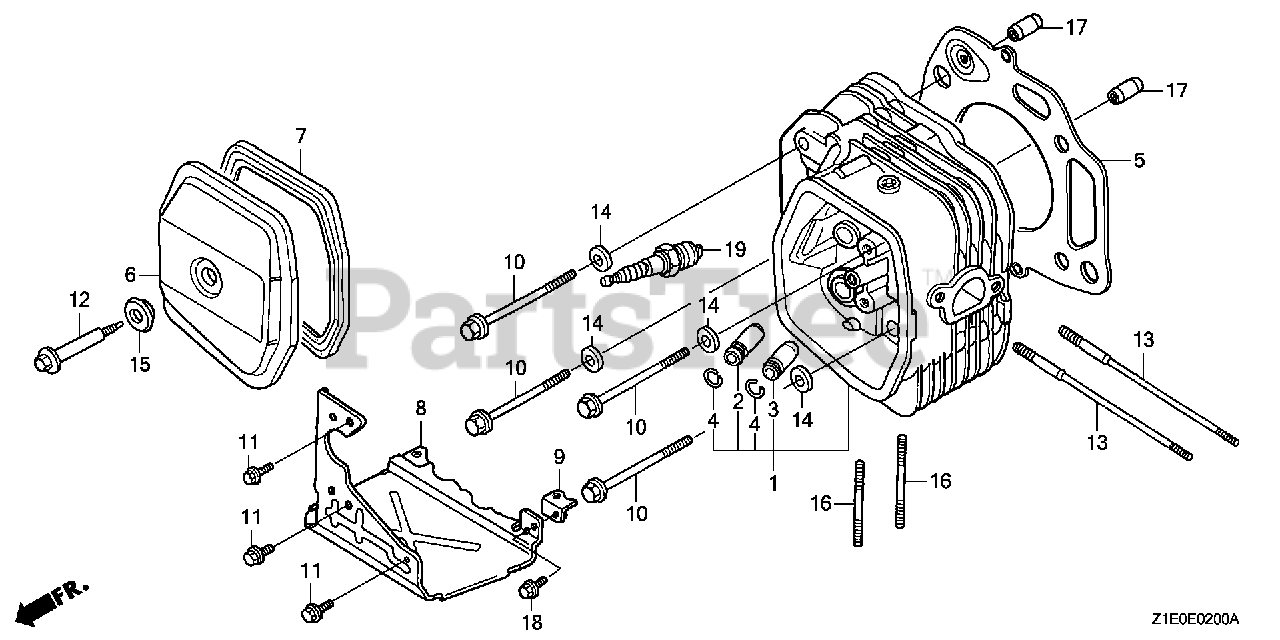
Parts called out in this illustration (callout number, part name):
1	CYLINDER HEAD
4	CLIP, VALVE GUIDE
5	GASKET, CYLINDER HEAD
6	COVER, HEAD
7	GASKET, CYLINDER HEAD COVER
8	COVER (LOWER)
9	STAY, COVER (LOWER)
10	BOLT, FLANGE (10X85)
11	BOLT, FLANGE (6X12) (CT200)
12	BOLT, HEAD COVER
13	BOLT, STUD (8X131.5)
14	WASHER, PLAIN (10MM)
15	WASHER, HEAD COVER
16	BOLT, STUD (8X32)
17	PIN A, DOWEL (12X20)
18	BOLT, FLANGE (6X12) Use up to Engine SN 1543277.
19	SPARK PLUG (BPR5ES) (NGK)
